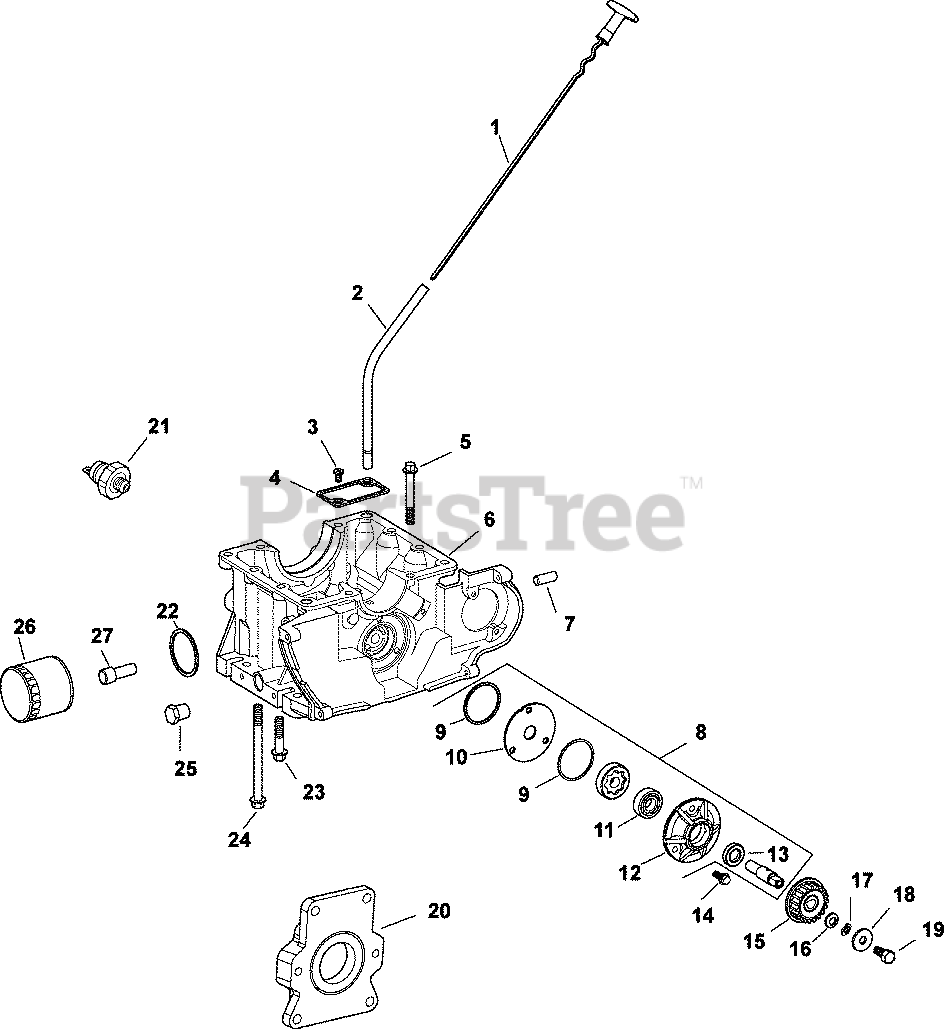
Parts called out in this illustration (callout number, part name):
1	DIPSTICK - DISCONTINUED
2	TUBE, DIPSTICK - DISCONTINUED
3	SCREW, TORX COUNTRSUNK HD
4	SCREEN, OIL PICK-UP - (#DSC)
5	SCREW, FLG M8X1.25X70
6	CRANKCASE
7	VALVE, PISTON RELIEF
8	PUMP ASSEMBLY, OIL - DISC.
9	O-RING - DISCONTINUED
10	PLATE, WEAR - DISCONTINUED
11	BEARING, BALL
12	COVER, OIL PUMP - DISCONTINUED
13	SEAL, OIL - DISCONTINUED
14	SCREW, FLG M6x1.0x20
15	SPROCKET, OIL PUMP - (#DSC)
16	WASHER, SPRING 13 MM
17	WASHER, SPRING LOCK 1/4"
18	WASHER, FLAT 1/4"
19	SCREW, HEX HEAD MACHINE
20	ADAPTER, OIL FILTER
21	SWITCH, PRESSURE (CLOSED)-USE 25 099 27-
22	O-RING - DISCONTINUED
23	SCREW, FLG M8X1.25X40 - (#M851040S)
24	SCREW, FLG M8X1.25X115
25	PLUG, HD PIPE 3/8"
26	FILTER, OIL
27	NIPPLE, OIL FILTER
